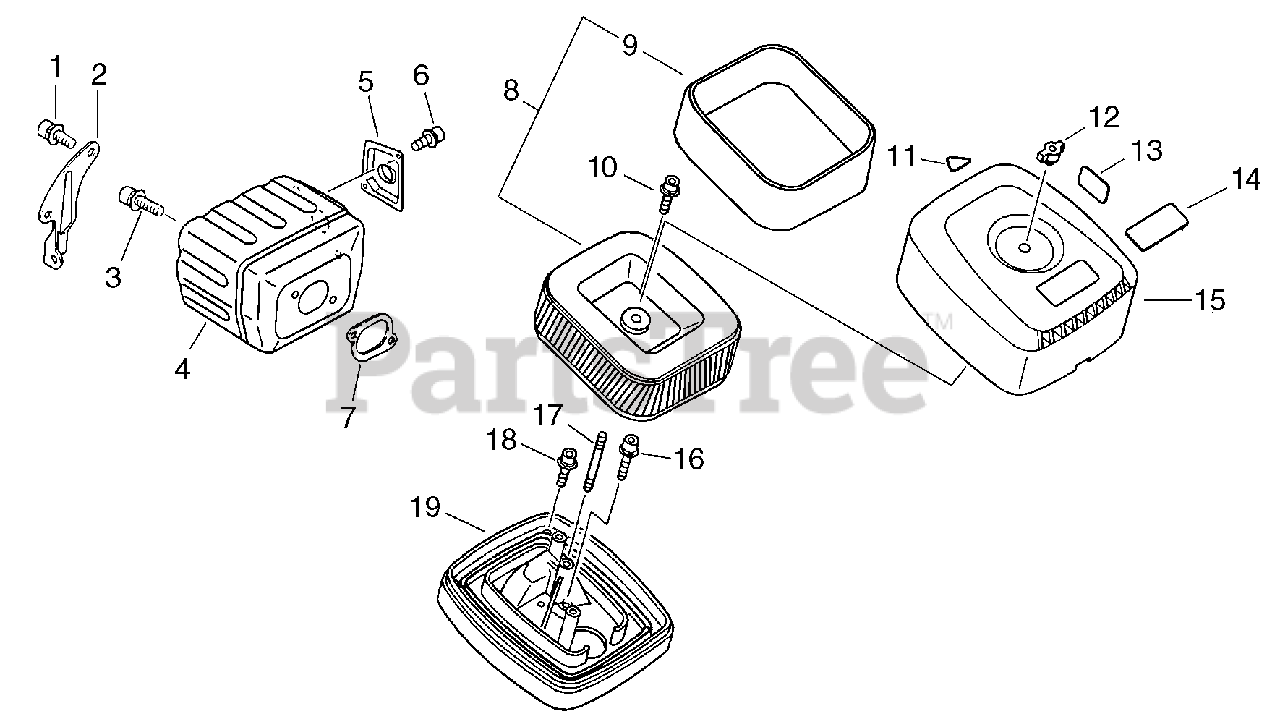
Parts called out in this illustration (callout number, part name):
1	SCREW - 5X14
2	BRACKET, MUFFLER
3	SCREW - 5X20
4	MUFFLER
5	GUIDE, EXHAUST
6	SCREW - 4X10
7	GASKET, EXHAUST
8	FILTER, AIR
9	FILTER, AIR
10	SCREW - 5X16
12	NUT
13	LABEL - CAUTION
14	LABEL - MODEL CSG-680
15	COVER, AIR FILTER
16	SCREW - 5X25
18	SCREW - 5X16
19	CASE, AIR FILTER
